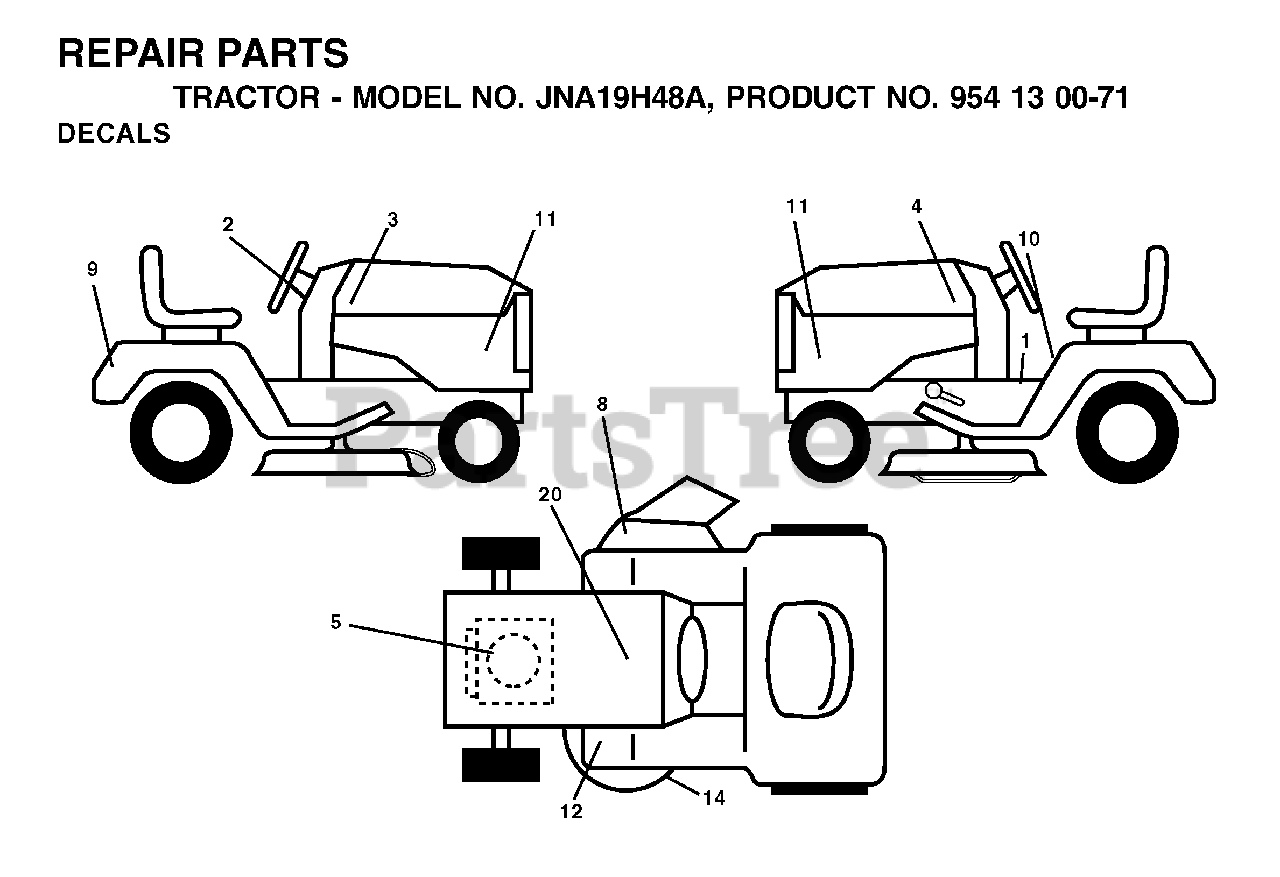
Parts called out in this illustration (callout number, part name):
1	DECAL SET
8	DECAL.WARN.KEEP.HAND.AWAY
10	DECAL FENDER DANGER
12	DECAL CLUTCH/BRAKE
14	DECAL V-BELT SCHEMATIC
20	DECAL BTRY SYMBOLS
